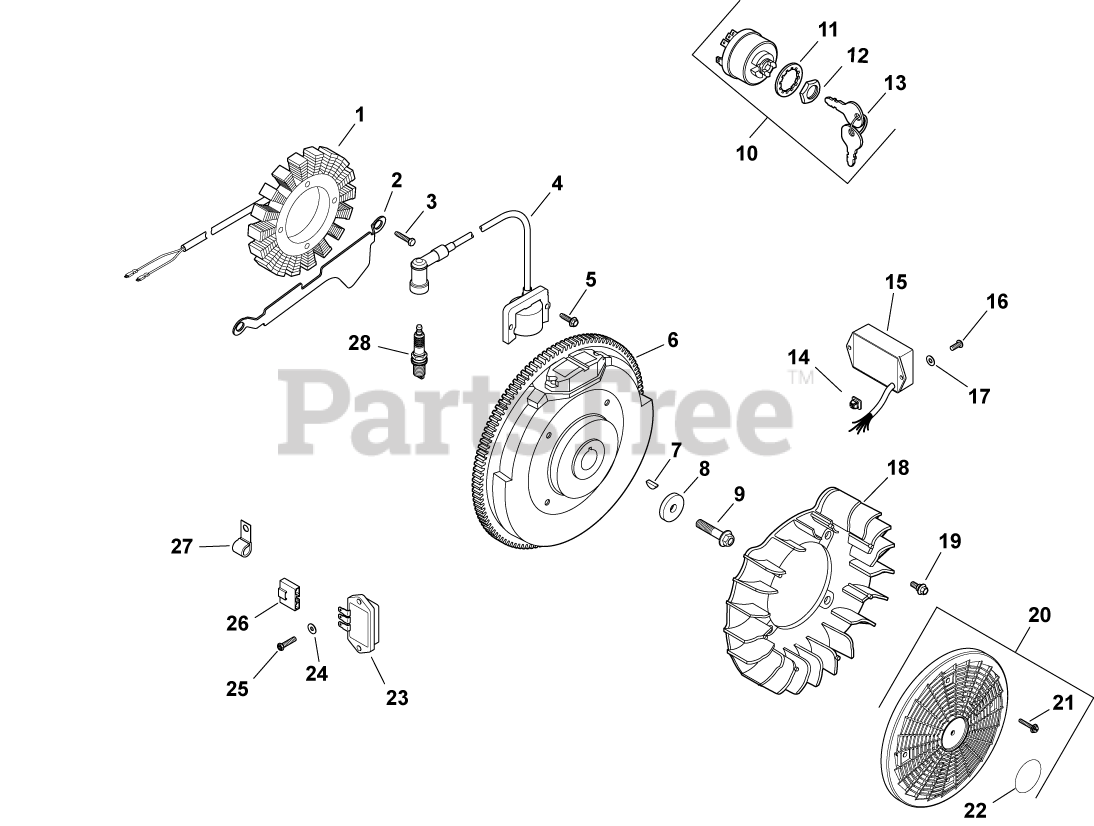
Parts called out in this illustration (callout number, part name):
1	KIT, 15 / 20 AMP STATOR
2	BRACKET, STATOR WIRE
3	SCREW, M5X0.8X25 - (#25086402S)
4	MODULE, IGNITION
5	SCREW, SKT THD FRM M5X0.8X25
6	FLYWHEEL ASSEMBLY (LW)
7	KEY, 3/16" X 5/8"
8	WASHER, FLAT 13/32"
9	SCREW, FLG M10X1.5X45 - (#25086361S)
10	SWITCH ASSY, KEY (KM)-USE 25 099 32-S
11	WASHER, INTERNAL TOOTH
12	NUT, KEY SWITCH
13	KEY, SET OF 2
14	NUT, PLASTIC
15	MODULE, SPEED ADVANCE-DISCONTINUED SEE PB265
16	SCREW, PHL HD #11-16X1/2"
17	WASHER, FLAT 1/4" (O.D. 1/2")
18	FAN USE 24 157 11-S
19	BOLT, SHOULDER
20	KIT, GRASS SCREEN
21	SCREW, SLT HD CAP M4X0.7X25
22	DECAL, GRASS SCREEN USE 24 113 499-S
23	REG/RECT-15 AMP (KM)-USE 41 403 10-S
24	WASHER, FLAT 3/16"
25	SCREW, PHL HD #11-16X7/8"
26	CONNECTOR
27	CLIP, CABLE
28	PLUG, SPARK (STD)
